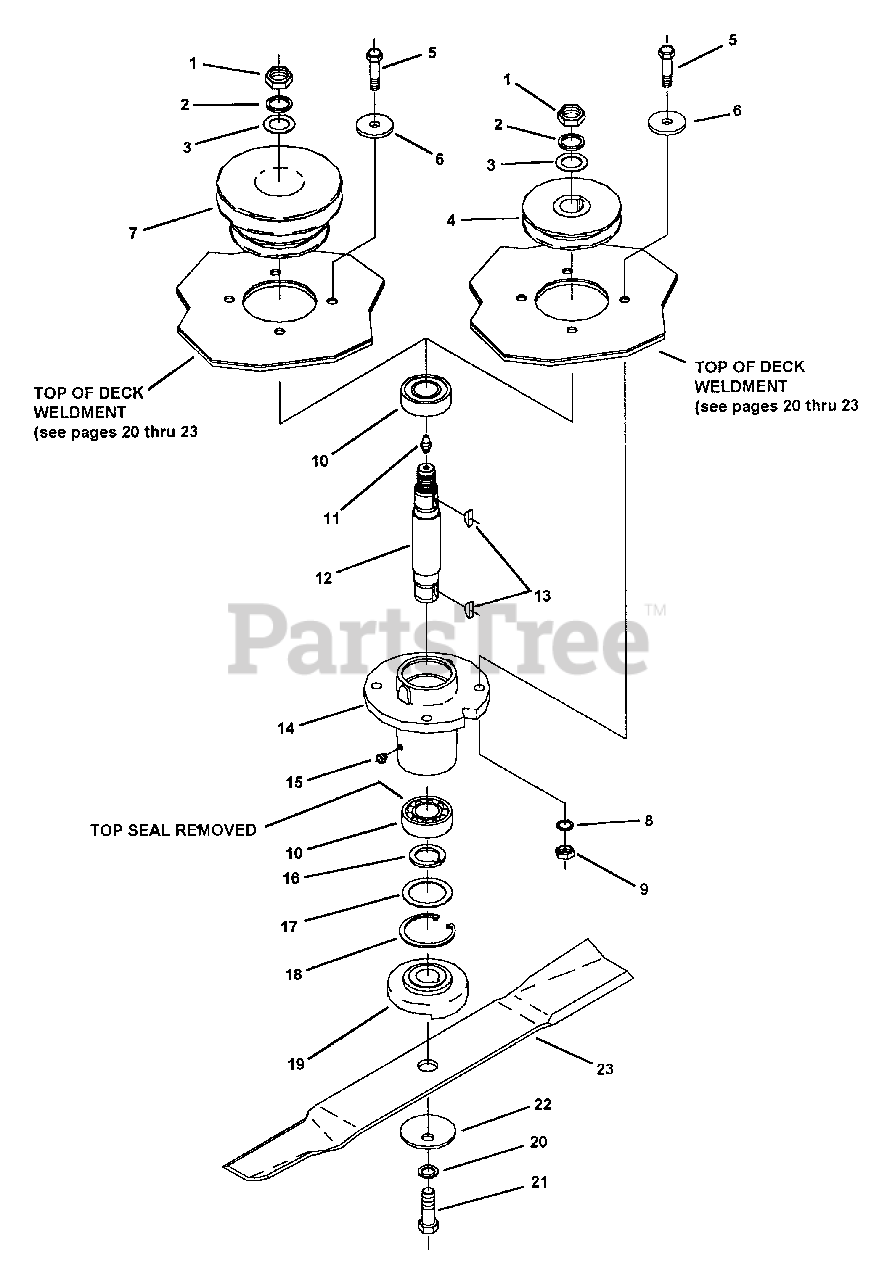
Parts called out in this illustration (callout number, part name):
1	NUT, HEX JAM, 3/4-16 UNF
2	LOCKWASHER, 3/4" STD. SPLIT SPRING
3	WASHER, 3/4" FLAT TYPE B NARROW
4	PULLEY, 1 GROOVE 4" O.D.
5	BOLT, 3/8-24 X 1-1/2" GR. 5
6	SPINDLE SPACER REINFORCEMENT
7	PULLEY, 2 GROOVE,
8	LOCKWASHER, 3/8" HEAVY SPRING TYPE
9	LOCKNUT, 3/8-24 M-F
10	BEARING, #6205-2RS
11	GREASE FITTING, 1/4-28 SELF TAP
12	SPINDLE SHAFT
13	WOODRUFF KEY, UASS #806, 1/4 X 3/4"
14	SPINDLE HOUSING
15	GREASE VENT
16	ARBOR SPACER
17	WASHER SEAL
18	SNAP RING, INTERNAL, 52 MM BORE
19	BLADE SPACER
20	LOCKWASHER, 1/2" STD. SPLIT SPRING
21	BOLT, 1/2-13 X 1-1/2" GR. 5
22	WASHER, 1/2" CUPPED
23	BLADE, LOW LIFT, 17" CUT, 48" DECK
